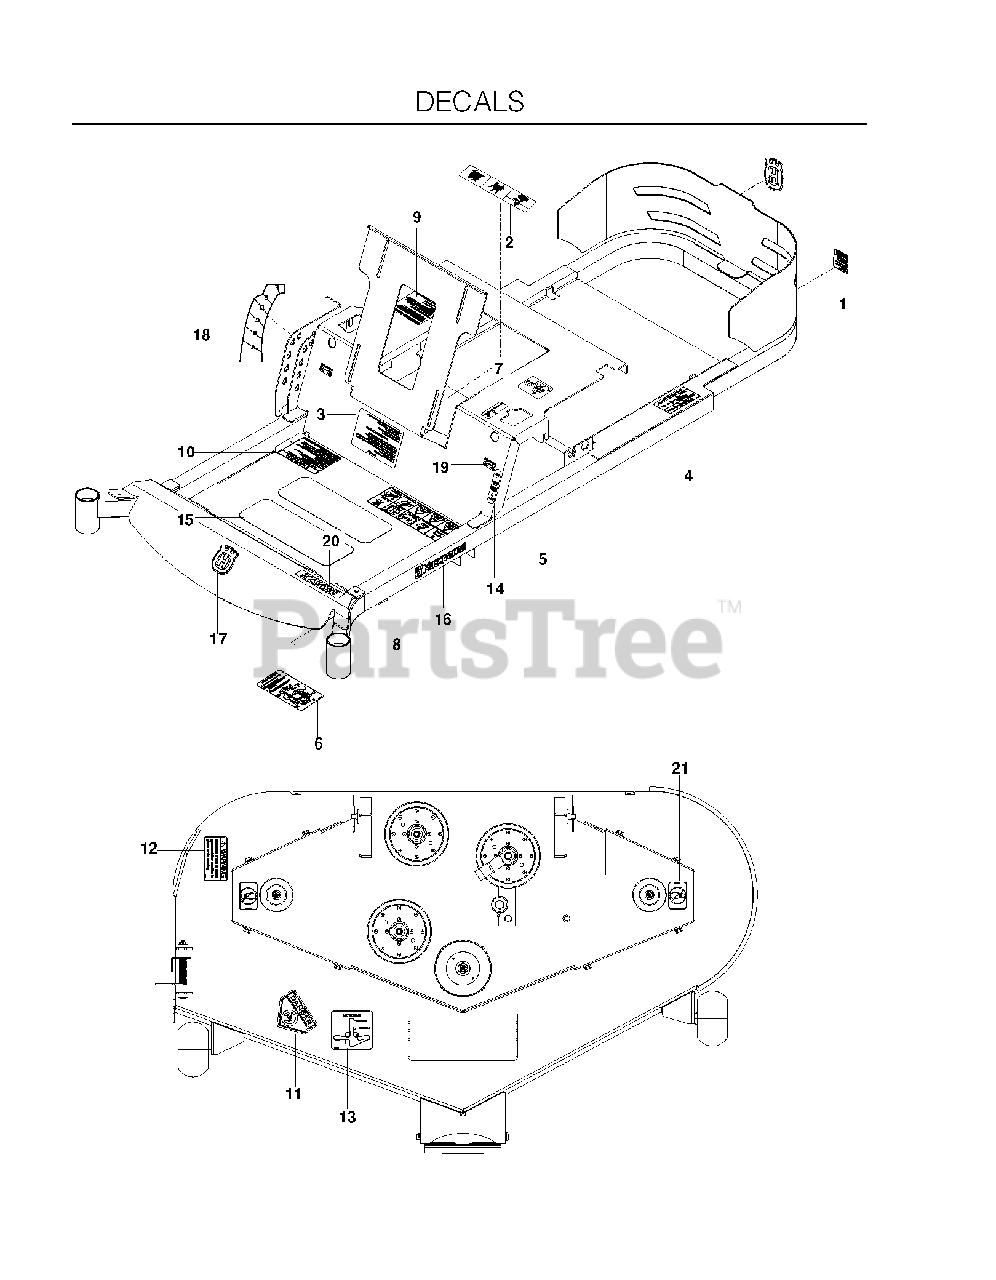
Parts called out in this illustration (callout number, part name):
1	DECAL, PROP. 65
2	EURO DECAL-BATTERY WARNIN6
3	DECAL, START
4	DECAL, DO NOT TOW
5	DECAL, EXITING MOWER
6	DECAL, SERVICE
7	DECAL, MOTION CONTROL
8	DECAL, SAFETY WARNING
9	DECAL, CUSTOMER RESPNSIBILITY
10	DECAL, WARNING
11	DECAL, CPSC
12	DECAL, CAUTION
13	DECAL, BELT ROUTING
14	DECAL, PARK BRAKE
15	ANTI-SKID PAD
16	RP.DECAL.BADGE.170MM.TEXTLOGO
17	DECAL.AUGER.HUSQ.CROWN.SNOW
18	DECAL, HEIGHT
19	DECAL, F.S.T.
20	DECAL, EZ4824
21	DECAL, NO STEP
